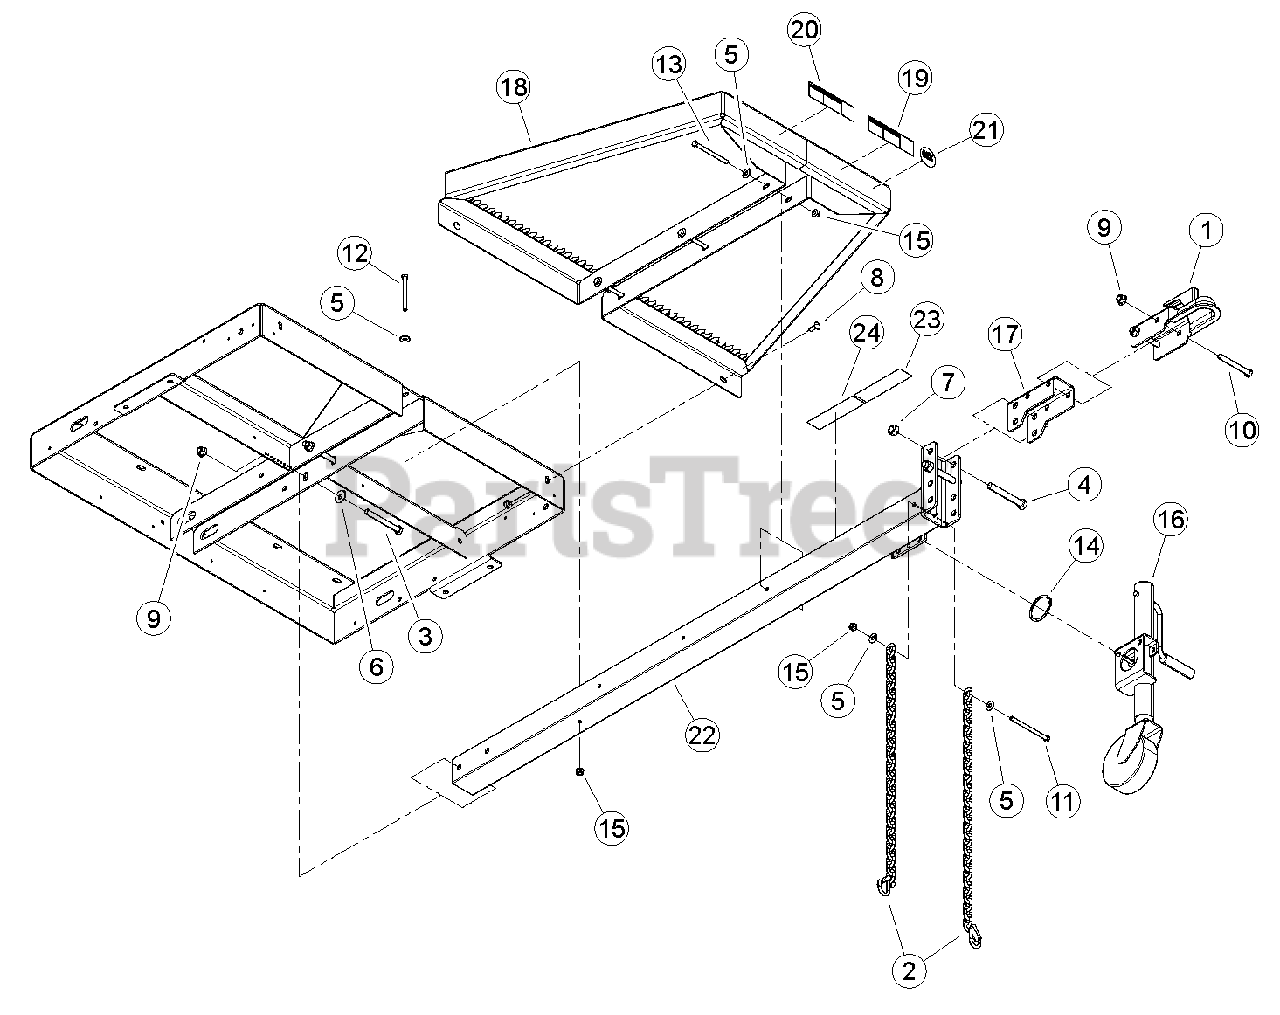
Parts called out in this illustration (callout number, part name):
1	COUPLER, 2 IN
2	CHAIN, SAFETY 5000 LB W/ LATCH
3	BOLT, 1/2 X 4-1/2" GR5 HHCS NC ZP
4	BOLT, 5/8 X 4-1/2 HEX HD G5 ZP
5	WASHER, 3/8 FLAT
6	WASHER, 1/2 FLAT
7	NUT, 5/8" CENTERLOCK ZP GR5
8	BOLT, 3/8-16 X 1 GR5 CRG
9	NUT, 1/2-13 NYLOCK FLANGE
10	BOLT, 1/2 X 4 HEX CPS G5 ZP
11	BOLT, 3/8 X 5" GR5 HEX CPS ZP
12	BOLT, 3/8 X 4" HHCS GR5 NC ZP
13	BOLT, 3/8 X 4-1/2" HHCS GR5 NC ZP
14	SNAP RING, 2-1/2 EXTERNAL
15	NUT, 3/8-16 NYLOCK FLANGE
16	JACK, PIVOTING W/ SWIVEL CASTOR
17	MOUNT, COUPLER
18	ASSEMBLY, STORAGE HITCH
19	DECAL, TRAILER ELECTRICAL
20	DECAL, CHECK WHEELS
21	DECAL, NATM COMPLIANCE
22	ASSEMBLY, DL HITCH
23	DECAL, SAFETY CHAINS
24	DECAL, SAFE COUPLING
